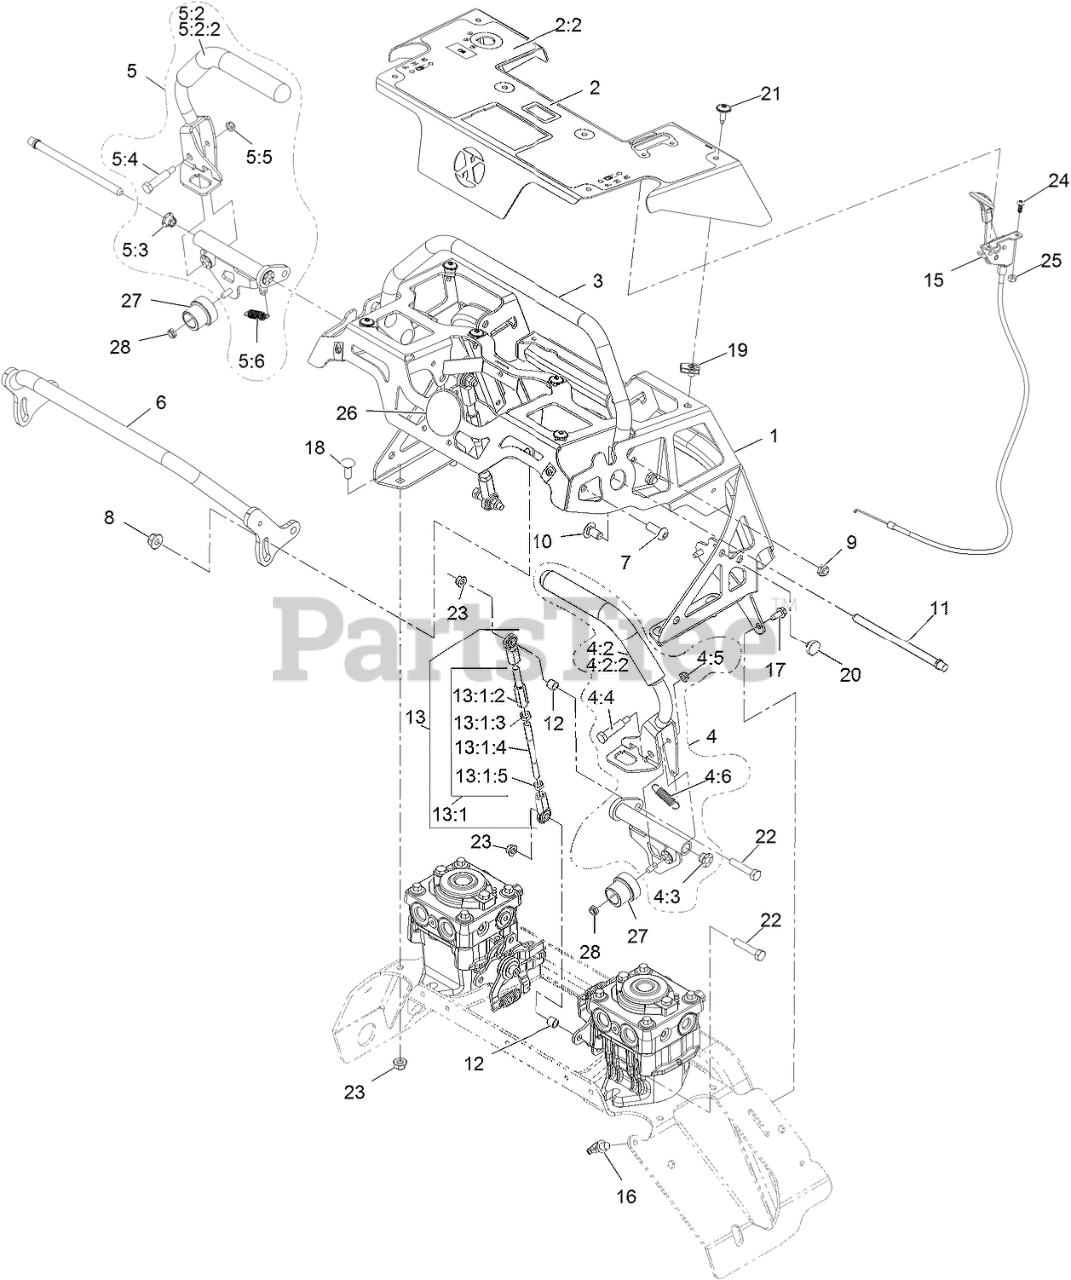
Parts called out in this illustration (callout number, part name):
1	ASM, Control Tower W/Decal
2	ASM, Control Panel W/Decal
2:2	Decal-Control Panel EFI
3	Weld, Rear Ref Bar
4	ASM, Motion Control, Lt
4:2	ASM, Lt Control Lever W/ Grip
4:2:2	Grip, Drive Lever
4:3	Bearing, Igus
4:4	BOLT-SHOULDER
4:5	NUT-LOCK, NI
4:6	SPRING-EXTENSION
5	ASM, Motion Control, Rt
5:2	ASM, Rt Control Lever W/ Grip
5:2:2	Grip, Drive Lever
5:3	Bearing, Igus
5:4	BOLT-SHOULDER
5:5	NUT-LOCK, NI
5:6	SPRING-EXTENSION
6	Weld, Front Ref Bar
7	SCREW-HSBH
8	NUT-HF, NI
10	SCREW-CARR
11	PIN, PIVOT
13	ASM, Linkage
13:1	ASM, Motion Control Link
13:1:2	ROD-ADJUSTMENT
13:1:3	NUT-HEX JAM, LH
13:1:4	Link, Motion Control
13:1:5	NUT-HJ
15	CABLE, THROTTLE
16	CLIP-TIE
17	SCREW-HWH
18	SCREW-CARR
21	Screw, Torx
22	SCREW-HH
23	NUT-HF, NI
24	SCREW, BHCS
25	NUT-LOCK, NI
26	Decal-Cover
28	NUT-LOCK, NI
